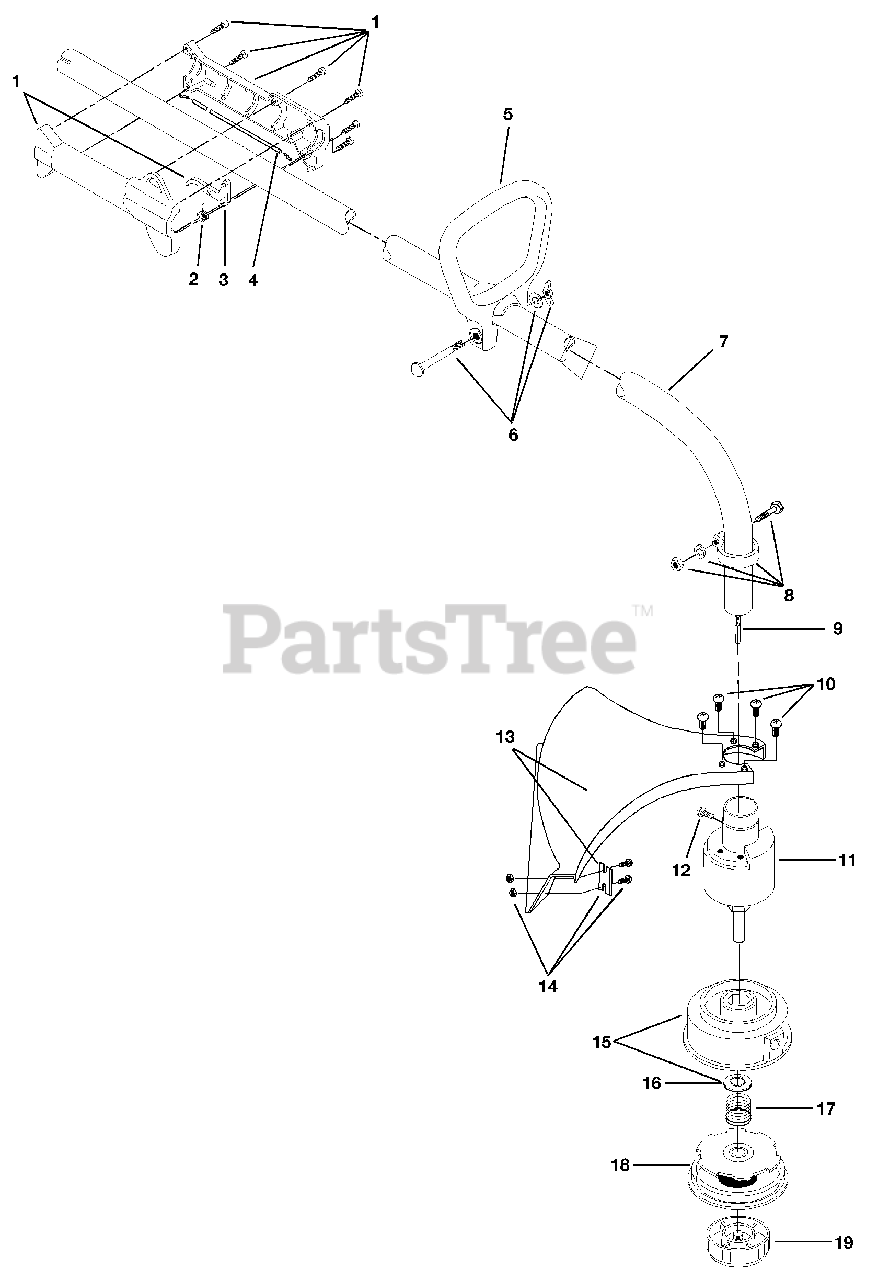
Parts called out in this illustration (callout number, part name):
1	Throttle Housing and Trigger Assembly
2	Throttle Trigger Spring
3	Throttle Trigger
4	Throttle Cable Assembly
5	D-Handle Assembly
6	D-Handle Hardware
7	Drive Shaft Housing Assembly
8	Lower Clamp Assembly
9	Flexible Drive Shaft
10	Shield Mounting Screw
11	Bushing Housing Assembly with Spool Shaft
12	Anti-Rotation Screw
13	Shield and Blade Assembly
14	Blade Assembly
15	Outer Spool and Eyelet Assembly
16	Retainer
17	Spring
18	Inner Reel
19	Bump Head Knob Assembly
